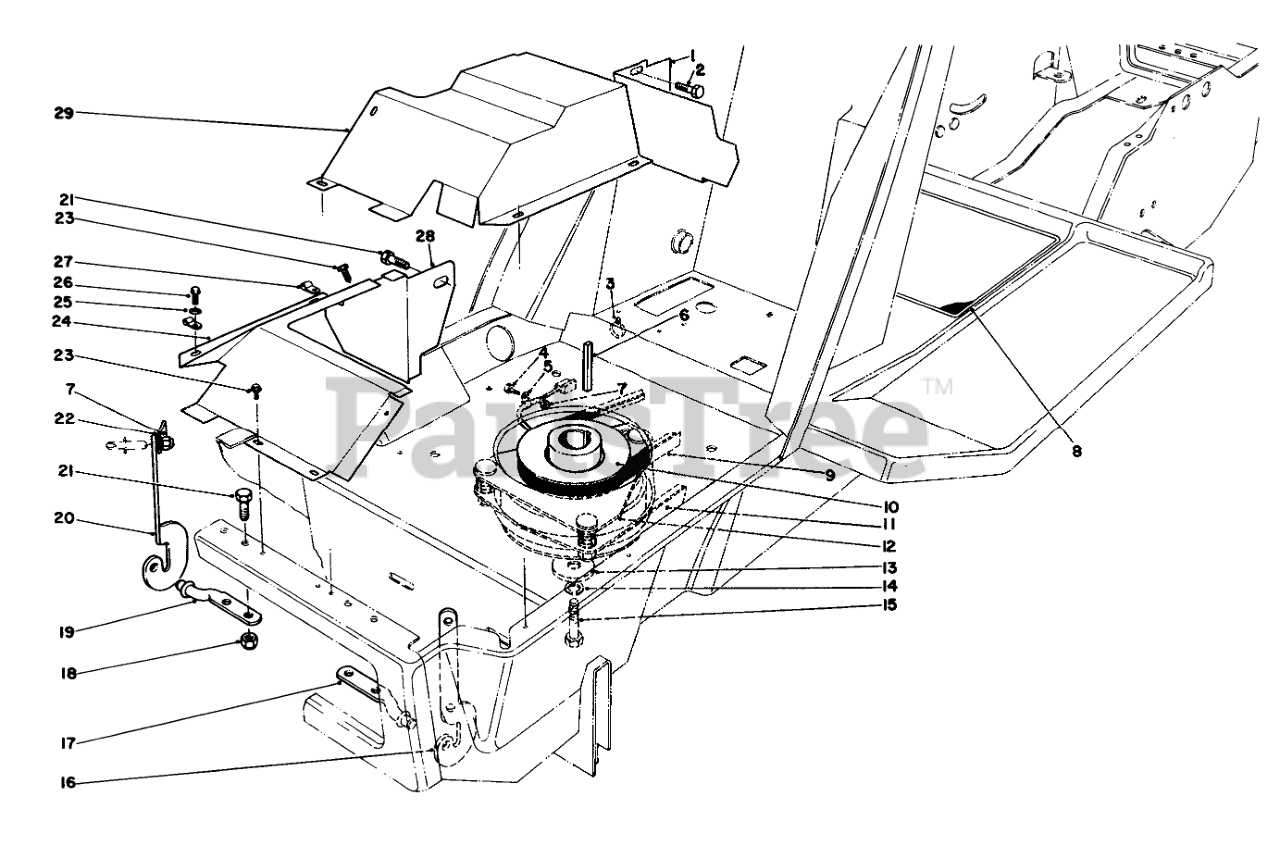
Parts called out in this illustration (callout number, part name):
1	EXH SHIELD SUPT B
2	SCREW-HH
3	TIE-MOUNT, PUSH
4	SCREW-HH
5	CLAMP
6	KEY-SQUARE
7	NUT-LOCK, NI
8	OPERATION DECAL
9	V BELT
10	Pulley
11	V BELT
12	Clutch Assembly-Deck
13	WASHER-CLUTCH
14	WASHER-LOCK
15	SCREW-HH
16	L.H. HINGE BRACKET
17	LH HOOD HINGE PIN
18	NUT-LOCK, CONE
19	RH HOOD HINGE PIN
20	RH HINGE BRKT
21	SCREW-HH
22	SCREEN SUPT BRKT
23	SCREW-HWHTF
24	Heat Shield
25	WASHER-FLAT
26	SCREW
27	CABLE CLAMP
28	Support Heat Shield
29	HEAT SHIELD WA B
